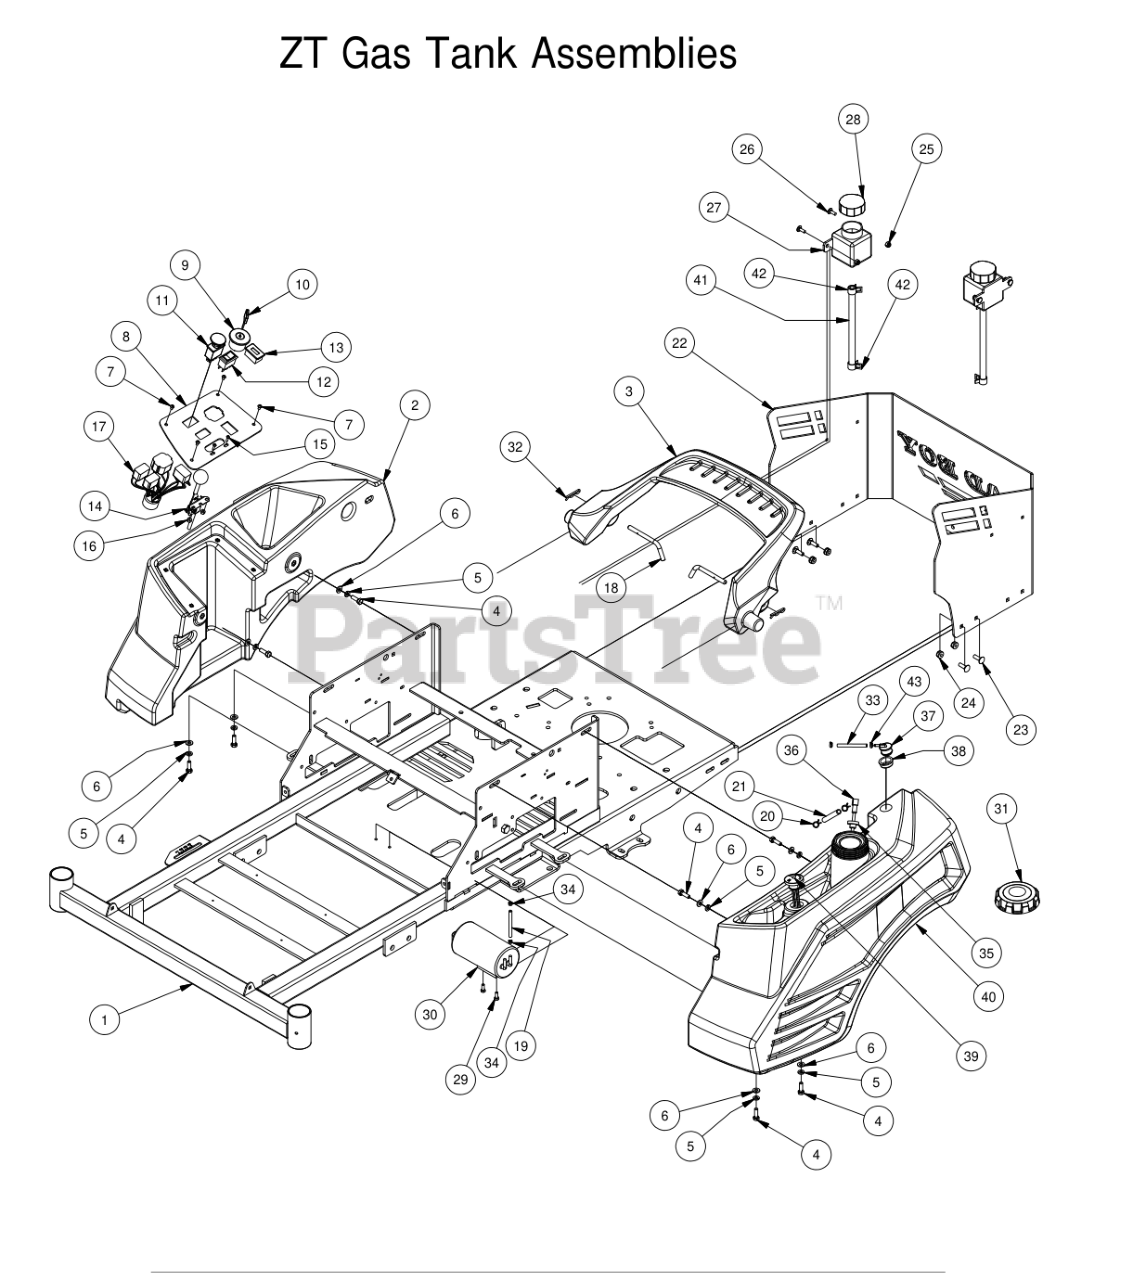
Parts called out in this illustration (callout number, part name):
2	2014 ZT Right Side Console
3	2014 ZT Spoiler
4	5/16" x 1" Bolt
5	5/16" Lock Washer
6	5/16" Flat Washer
7	10-32 x 3/8" Button Socket Head Bolt
8	Control Panel
9	Ignition Switch
10	Ignition Key
11	PTO Engager
12	Rocker Deck Lift Switch - 2011
13	Tachometer
14	Throttle Lever Assembly
15	10-24 X 5/8 BS Button Head Bolt
16	10-24 Nylon Insert Locknut
17	Wire Harness
18	Bent Pin-2014 ZT Spoiler
19	3/16 Vinyl Tubing
20	1/4 Fuel Hose Clamp
21	1/4" Fuel Line Hose
22	2014 ZT Rear Plate
23	5/16" x 1" Carriage Bolt
24	5/16-18 Nylon Flange Nut
25	1/4" Nylock Nut
26	1/4" x 3/4" Carriage Bolt
27	350ml Expansion Tank
28	Hydraulic Tank Cap
29	M6-1.0 X 16MM Hex Bolt
30	Carbon Canister
32	Cotter Ping-ZT Spoiler
33	1/4" Vinyl Tubing
34	3/16" Vinyl Hose Clamp
35	Pick-Up Grommet
37	Rollover Valve
38	Rollover Valve Grommet
39	Fuel Gauge w/Grommet
40	2014 ZT Left Fuel Tank
41	3/8" Clear Hose
42	3/8" Hose Clamp
43	1/4" Hose Clamp
